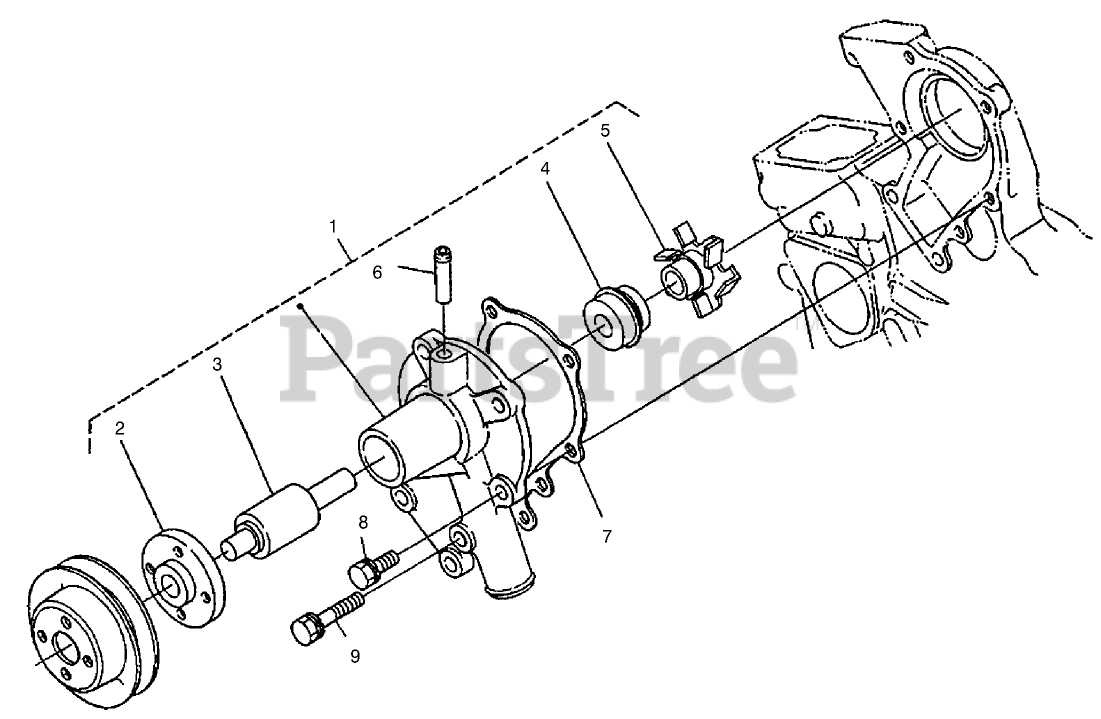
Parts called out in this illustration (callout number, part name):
1	WATER PUMP ASM
2	FLANGE-PUMP, WATER
3	BEARING-BALL
4	WATER PUMP SEAL ASM
5	IMPELLER-PUMP, WATER
6	PIPE-RETURN, WATER
7	GASKET-PUMP, WATER
